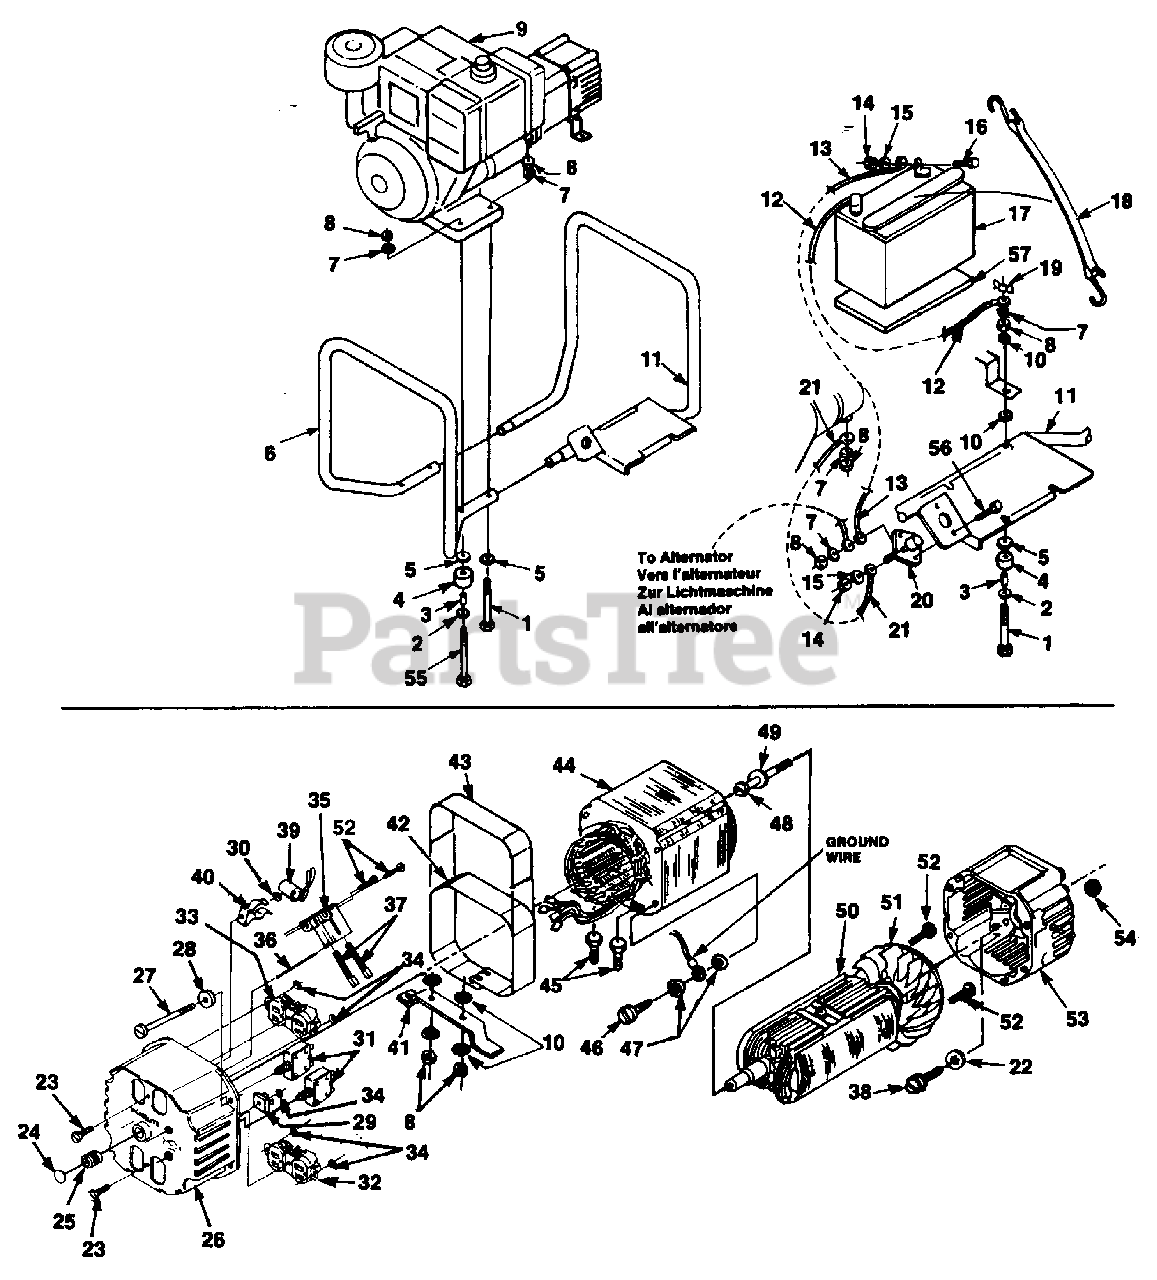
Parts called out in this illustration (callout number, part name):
2	WASHER- Flat (5/16")
3	SPACER- Foot
5	WASHER- Flat (5/16")
6	MEMBER- Frame (gen. end)
7	WASHER- Lock (int.)
8	NUT- Hex (5/167-18)
9	ENGINE
10	WASHER- Lock (ext./int.)
11	MEMBER & STARTER
13	CABLE (Battery to Solenoid)
14	NUT- Hex
15	WASHER- Lock
22	WASHER- Lock (3/8")
23	SCREW- Mach. pan hd.
24	PLUG- Expansion
25	BEARING- Needle
26	BRUSH HEAD
27	BOLT- Stator
28	WASHER- Flat
29	RECTIFIER
30	WASHER- Shaft retention
31	BREAKER- Circuit (20 amp.)
32	RECEPTACLE- (240V) (Nema 6-20R)
33	RECEPTACLE- Duplex (Nema 5-15R)
34	WASHER- Shaft retention
35	BRUSH HOLDER
36	PIN- Retaining
37	BRUSH
38	SCREW- (3/8-16 x 7/8")
39	CAPACITOR (w/Leads)
40	CLIP- Spring
41	BRACKET- Generator mtg.
42	WRAPPER- Stator
43	DECAL- Warning
44	STATOR
47	WASHER- Lock (int./ext.)
48	BOLT- Rotor
49	WASHER
51	FAN--Generator
52	SCREW- Pan hd.
53	BELL- End
54	NUT- Hex
55	SCREW- (5/16 x 3 1/4")
56	SCREW-Washer hex hd.
57	PAD- Battery
